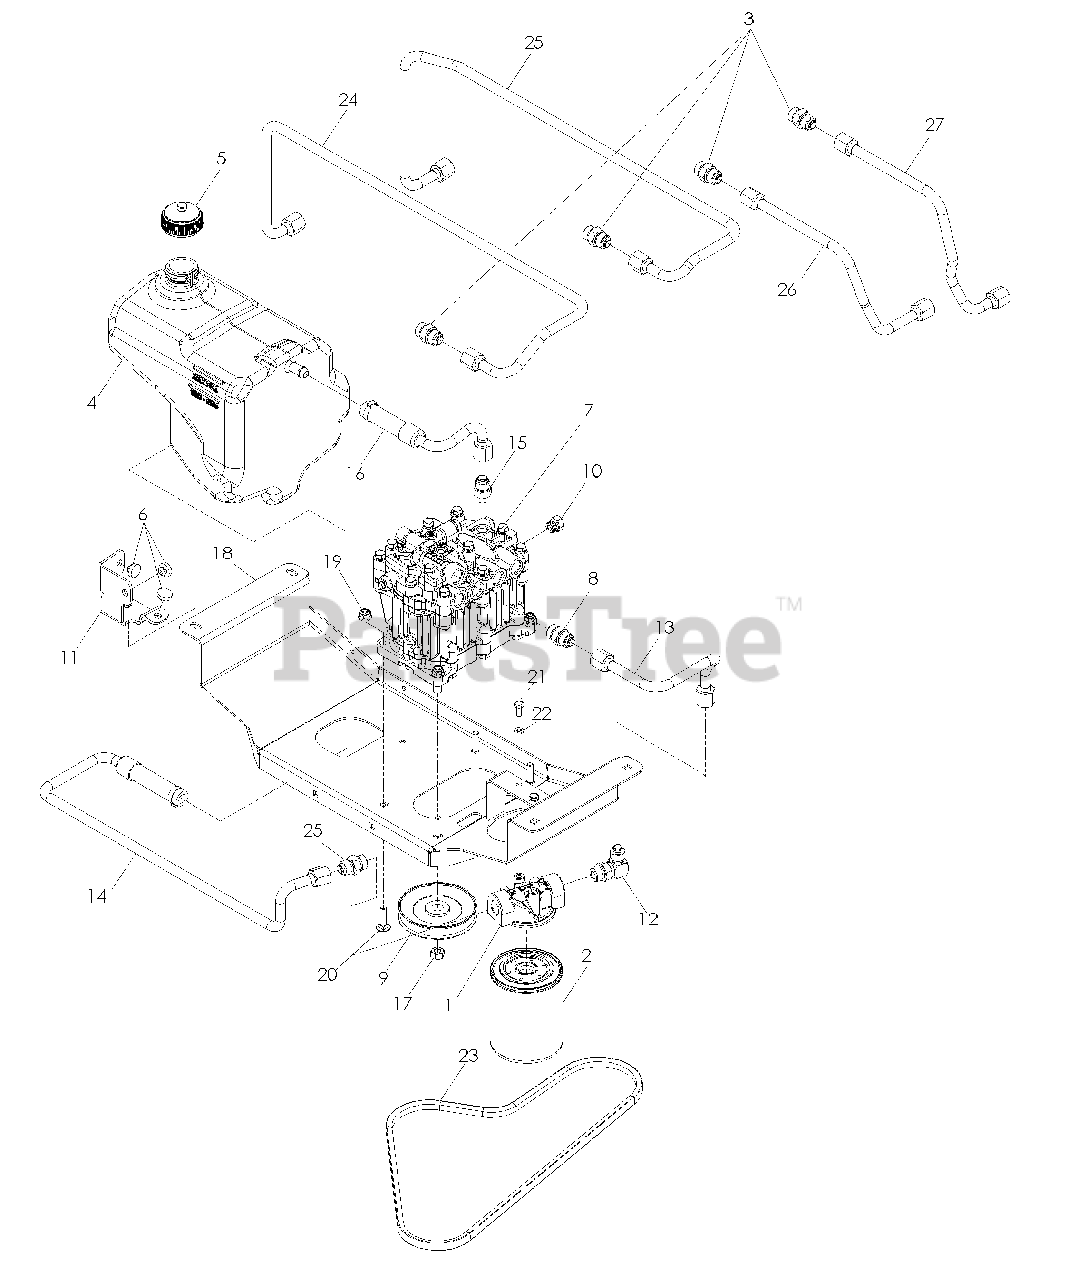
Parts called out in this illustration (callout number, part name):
1	FILTER HEAD
2	FILTER, OIL
3	STRAIGHT CONNECTOR
6	GROMMET, BUMPER
7	PUMP, DUP10S
8	FITTING, 10-8 STRAIGHT
9	PULLEY, PUMP
10	PLUG, 6408-6
11	SUPPORT, RESERVOIR
13	HYDRO LINE, CHARGE
14	HYDRO LINE, INLET
15	FITTING, HYDRO
16	HYDRO LINE, CASE
17	NUT M10-1.5 L/H HEX
18	PLATE, PUMP
19	NUT 5/16-18 FLANGE NYLOC
20	RHSNB 5/16-18 x 1 1/4
21	HCS 1/4-20 x 5/8
22	WASHER, 1/4 SPLIT LOCK
24	HYDRO LINE MODELS 968999717, 968999718, 968999720, 968999721, 968999748, 968999749, 968999780
24	HYDRO LINE MODEL 968999719
